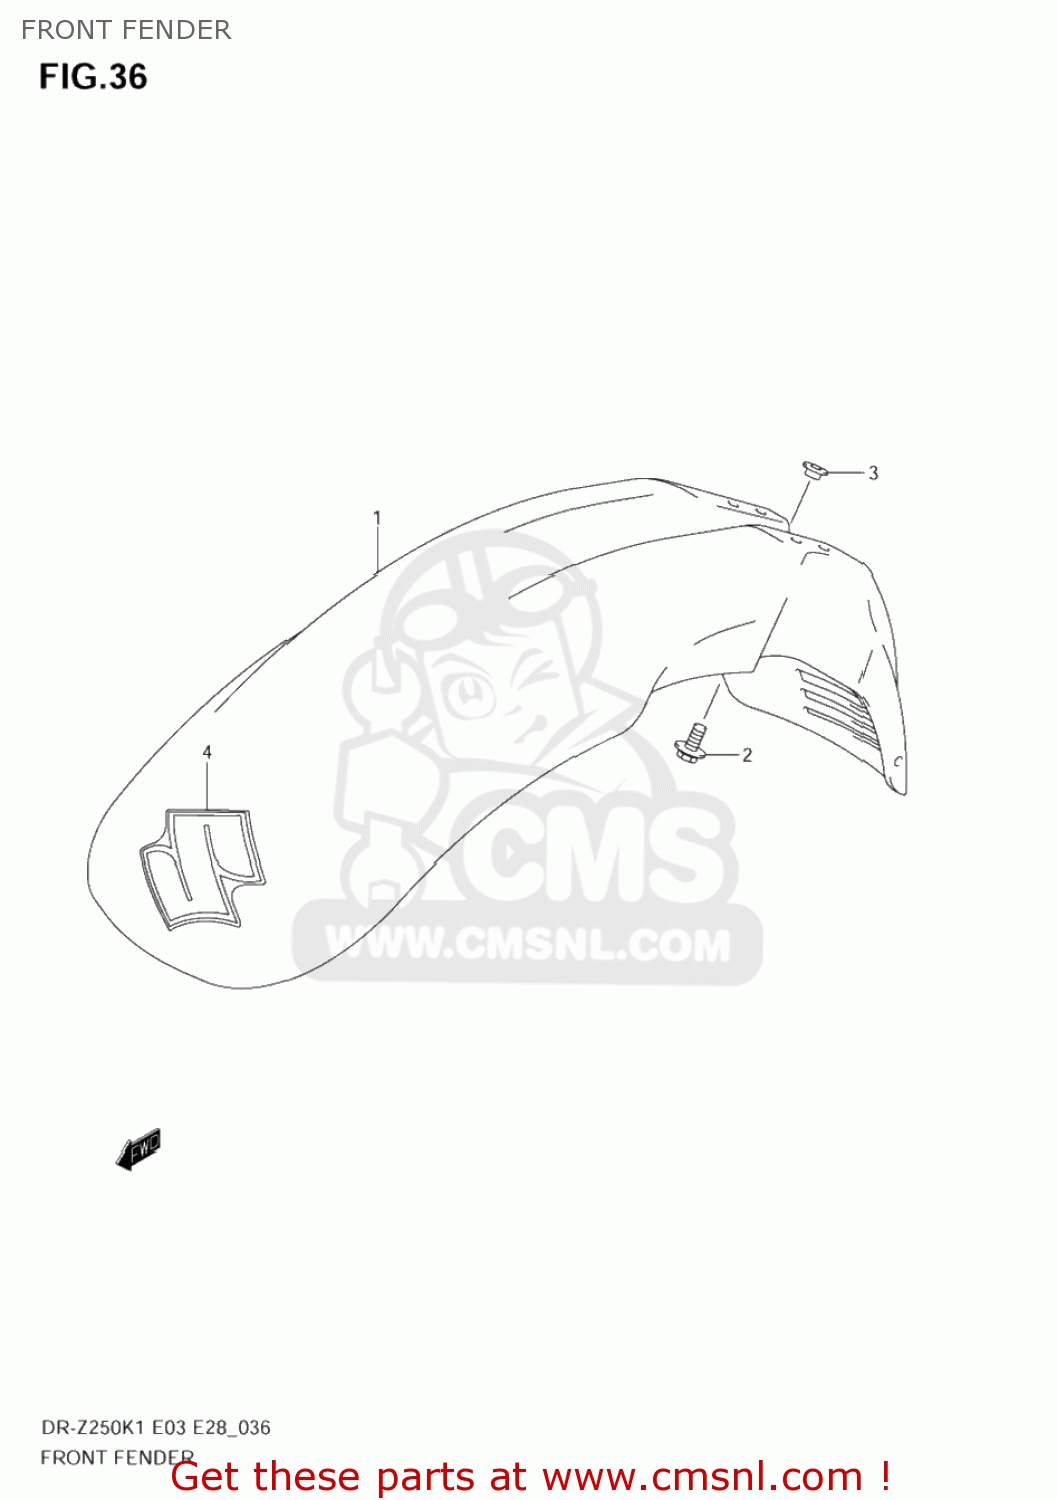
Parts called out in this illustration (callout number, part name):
1	FENDER,FR
2	BOLT(6X16)
3	WASHER
4	EMBLEM,S
